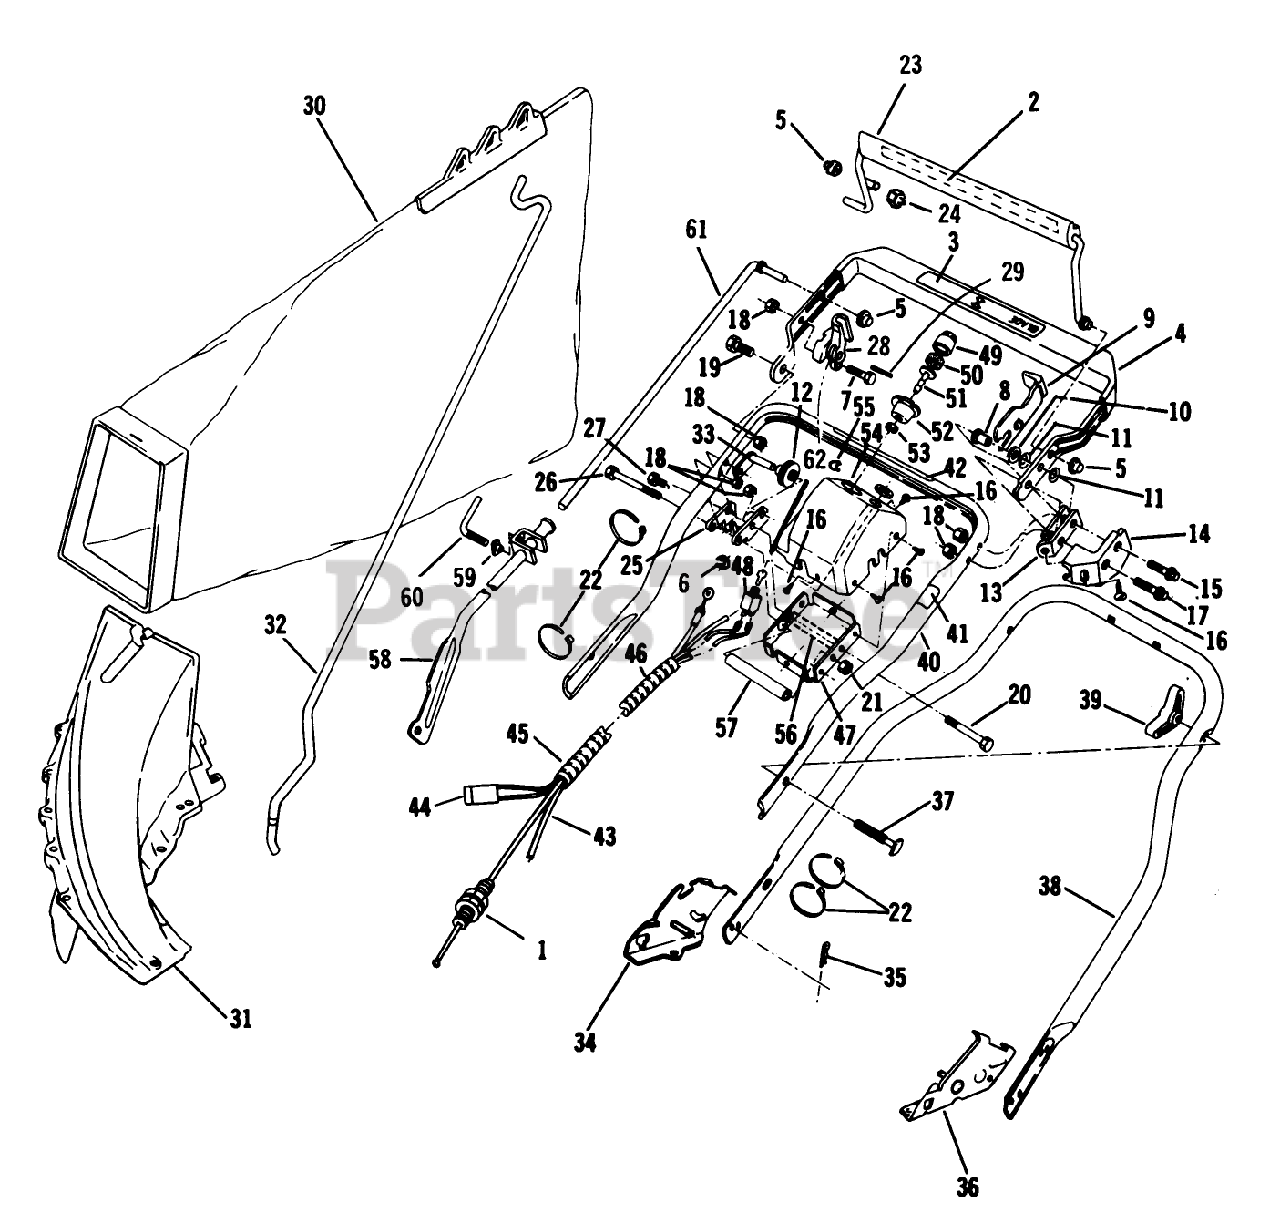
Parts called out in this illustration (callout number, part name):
1	CONTROL CABLE
6	RET. RING
8	SPACER
10	WASHER M
13	DOWN STOP
14	LOCKOUT GUARD
15	BOLT SHOU
16	SCREW F
17	SCREW
18	LOCKNUT E
19	BOLT
24	NUT ACORN
26	BOLT-CONSOLE
30	89802 LB WHOLE GOODS
32	ROD GRASSBAG
34	BRACKET ASM - HANDLE, SP, RH
35	HAIR PIN
36	BRACKET ASM - HANDLE, SP, LH
37	BOLT QUALITY
39	NUT-WING
50	FILTER S
53	LOCKNUT S
56	SPACER
61	CONTROL ROD
